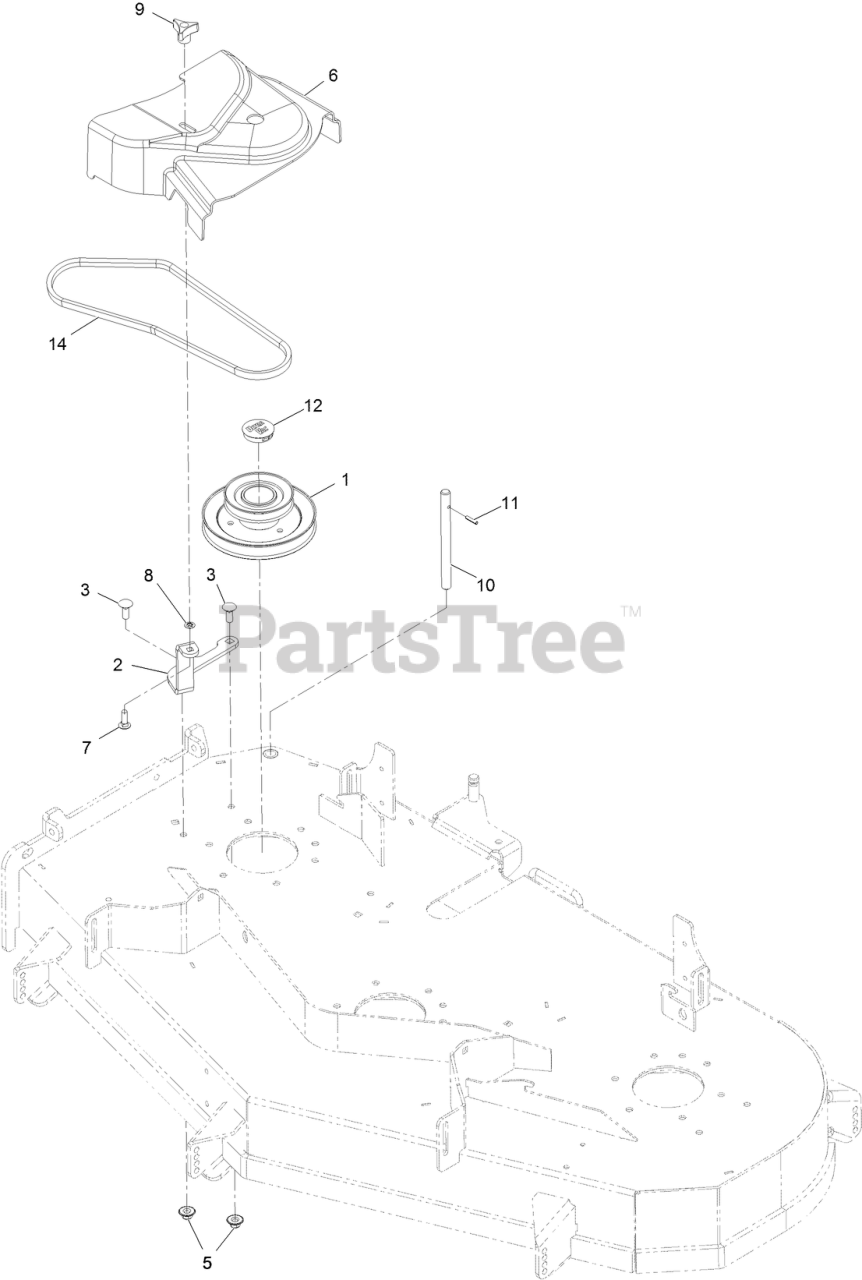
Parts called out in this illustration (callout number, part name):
1	JACKSHAFT,UV DRIVE 524 SPLINED
2	BRACKET, SMALL UV BELT COVER
3	BOLT-CARR
5	Nut-Nyloc 3/8-16 Flg
6	COVER-BELT, UV 52
7	BOLT-CARR
8	RING-RETAINING, BOLT
9	KNOB-3 PRONG
10	SHAFT-CATCHER, GRASS
11	PIN-ROLL
12	PLUG, BLACK NYLON 1.75
